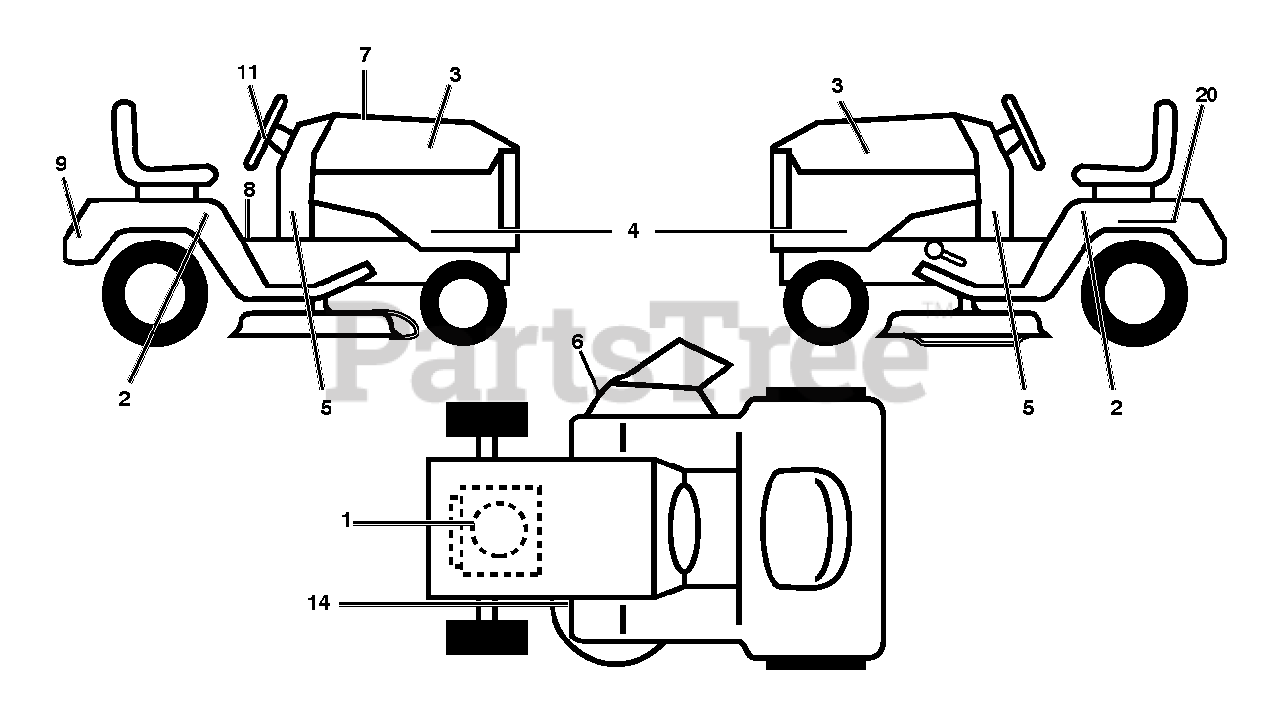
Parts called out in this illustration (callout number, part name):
2	DECAL.FEND.RH/LH.SET.6S.POULAN
3	DECAL.HOOD.ALPHA.RH/LH.POULAN
6	DECAL.WARN.DFLECT/CTFINGR.SRD
8	Fender Engine Warning Decal
9	DECAL.FEND.POULAN.2010
11	DECAL.WHEEL.STRG.STDHRS.POULAN
20	DECAL BTRY SYMBOLS
